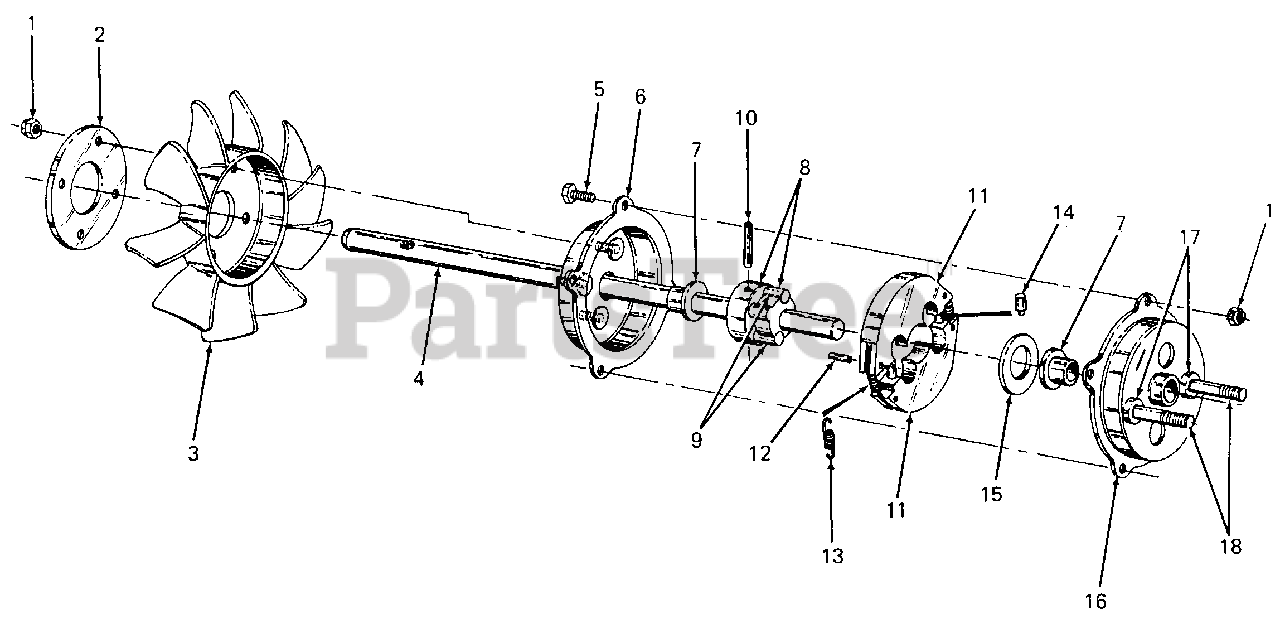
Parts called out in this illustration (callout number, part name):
1	Nut, Hex Patch Lock, 1/4-20
2	Spacer, Fan
3	Fan, Cooling
4	Shaft, Drive
5	Screw, Hex Cap, 1/4-20 X .50 Lg GR5
6	Cover Assy, Clutch
7	Bearing, Flange
8	Hub Assy, Clutch
10	Pin, Slotted, Roll, 1/4 X 2.25 Lg
11	Shoe Assy, Clutch
12	Pin, Spirol Spring, 1/8 Dia X 5/8 Lg
13	Spring, Extension, .31 X .85 Lg
15	Washer, Flat, .760 X 1.49 X.06 Thk Hdn
16	Housing, Clutch
17	Spacer, .385 X .88 X .25 Lg
18	Bolt, Ribbed Neck, 3/8-24 X 1.5 Lg GR5
